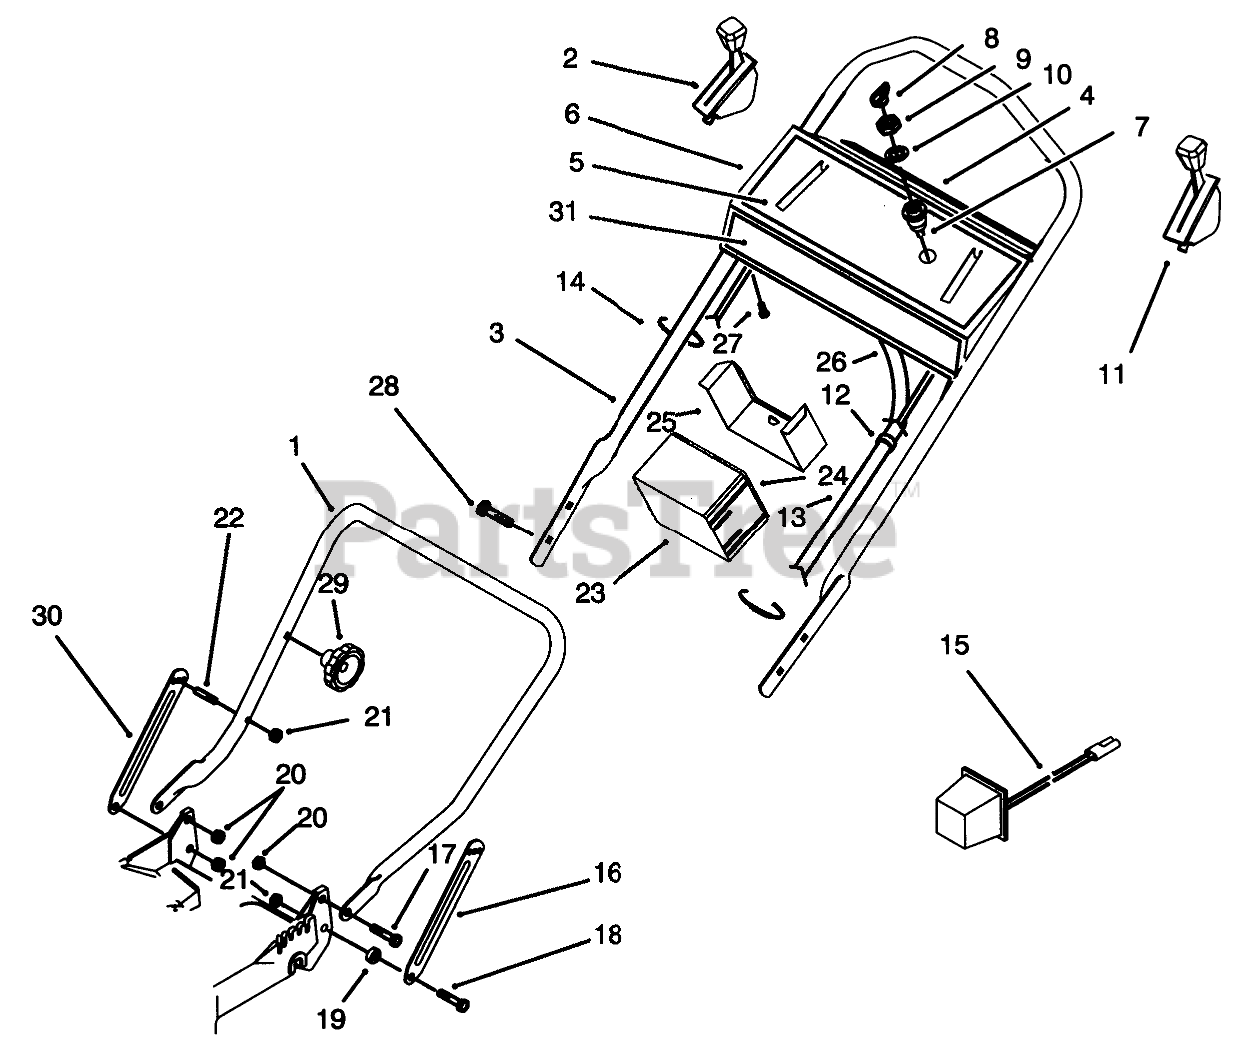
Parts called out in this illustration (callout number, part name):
1	LOWER HANDLE ASM
2	CONTROL-SPEED, GROUND
3	UPPER HANDLE, PVC DIP
4	DECAL - PANEL, REAR
5	DECAL - INSTRUCTION
6	Panel-Control (Incl. Ref. #4 & 5)
7	STARTER SWITCH ASM
8	KEY-IGNITION
9	NUT-HH
10	WASHER-TOOTH, INTERNAL
11	THROTTLE CONTROL
12	FITTING-RING
13	CONTROL CABLE COVER
14	TIE-CABLE
15	Charger
16	LH HANDLE LATCH
17	SCREW-SHOULDER
18	SCREW-SHOULDER
19	SPACER
20	NUT-LOCK, NI
21	NUT-LOCK, NI
22	HANDLE PIN
23	BATTERY ASSEMBLY
24	Decal
25	Retainer-Battery
26	Harness-Wire
27	10-16X1/2 SHWH SCREW
28	5/16-18 X 2 HNDLE SCREW
30	RH HANDLE LATCH
31	DECAL - TORO
